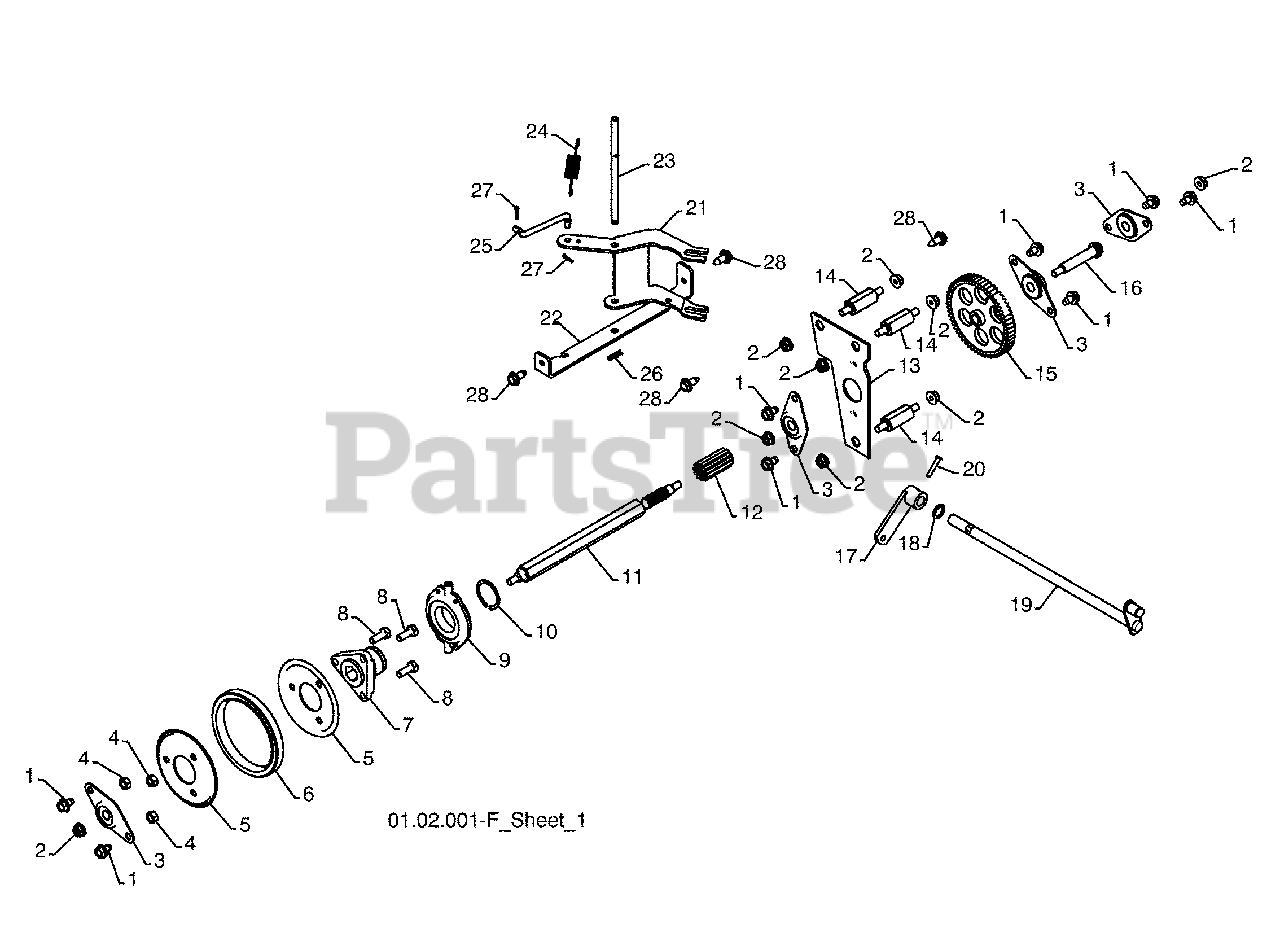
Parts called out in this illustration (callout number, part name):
1	BOLT 5/16-18 X .500
2	NUT 5/16-18
3	FLANGE BEARING
4	NUT 5/16-18
5	RUBBER WHEEL PLATE
6	RUBBER WHEEL RING
7	RUBBER WHEEL HUB
8	BOLT 5/16-18 X .875
9	TRUNNION BEARING ASSEMBLY
10	RETAINER
12	PINION GEAR
13	AUXILIARY PLATE
14	SPACER PLATE
15	INTERMEDIATE GEAR
16	AUXILIARY SHAFT
17	CONTROL ARM
19	CONTROL SHAFT ASSEMBLY
20	CLEVIS PIN
21	SHIFTER LEVER
22	PIVOT BRACKET
25	SHIFTER LINK
28	BOLT 5/16-18 x .750
